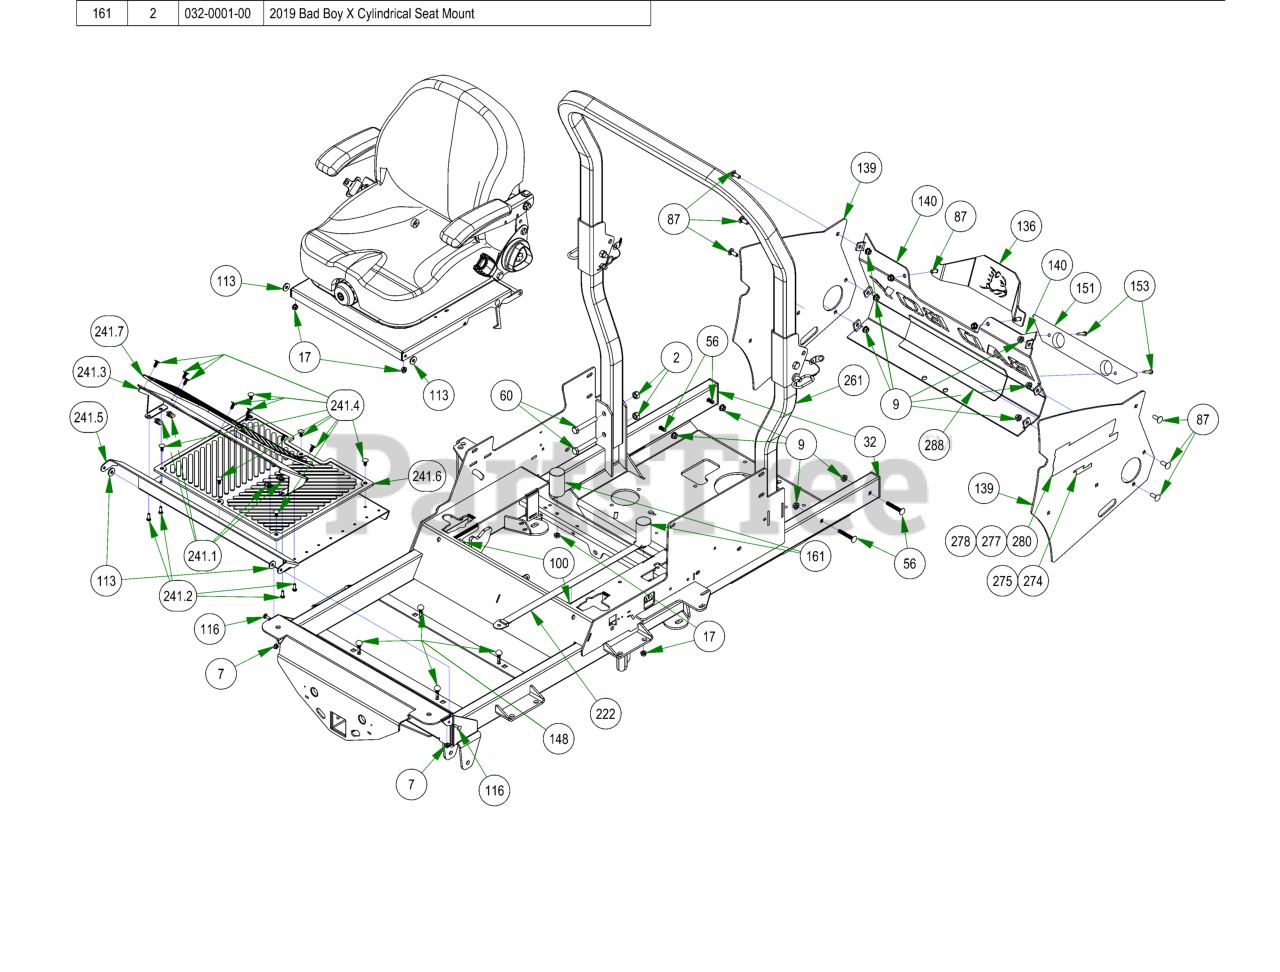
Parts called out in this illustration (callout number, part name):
2	1/2-13 HEX 2-WAY REVERSIBLE CENTER LOCKNUT Grade B ZINC
7	1/4-20 NYL INSERT FLANGE LOCKNUT ZINC
9	3/8-16 NYLON INSERT FLANGE LOCKNUT (GR.F) ZINC
17	5/16-18 NYLON INSERT FLANGE LOCKNUT ZINC
32	1 1/2 x 3 Frame Plug
56	3/8" x 2 1/2" Carriage Bolt
60	1/2-13 X 3-1/4 HEX CAP SCREW (GR.5) ZINC
87	3/8-16 X 1 CARRIAGE BOLT (GR.5) ZINC
100	5/16-18 X 1 CARRIAGE BOLT (GR.8) ZINC
113	.360 ID X .983 OD X .120 THICK FLAT WASHER NYLON
116	1/4-20 X 3/4 CARRIAGE BOLT (GR.5) ZINC
136	Kohler 980 Engine Shield
138	R-SERIES SEAT PLATE ASSEMBLY
139	2019 Rouge Rear Cover Side Plate
140	2019 Vertical Rear Cover Tailgate - Black
148	2023 Floor Board Rubber Bumper
151	2017 XP Bumper
153	1/4-14 X 1-1/2 HEX WASHER UNSLOT TEK/3 ZINC
161	2019 Bad Boy X Cylindrical Seat Mount
222	Seat Strap with Buckles
235	2023 Rogue Frame - Painted
241	R-Series Floorboard Assembly
241.1	1/4-20 Cage Nut
241.2	1/4-20 X 3/4 HEX CAP SCREW (GR.5) ZINC
241.3	OUTLAW ADJUSTABLE FOOT PLATE-ORANGE
241.4	Ratchet Fastener
241.5	2019 Outlaw Floorboard
241.6	MAT (FLOOR)
241.7	MAT (FOOT PLATE)
261	2019 2X2 Folding ROPS
274	2022 Powered By Kawasaki Decal
275	2022 Powered By Kohler Decal
277	2019 Rogue 852cc Backplate Cluster
278	2019 Rogue 999cc Backplate Cluster
280	Rogue 999cc-EFI Backplate Cluster
288	Heat Shield (Fiberglass Adhesive)
